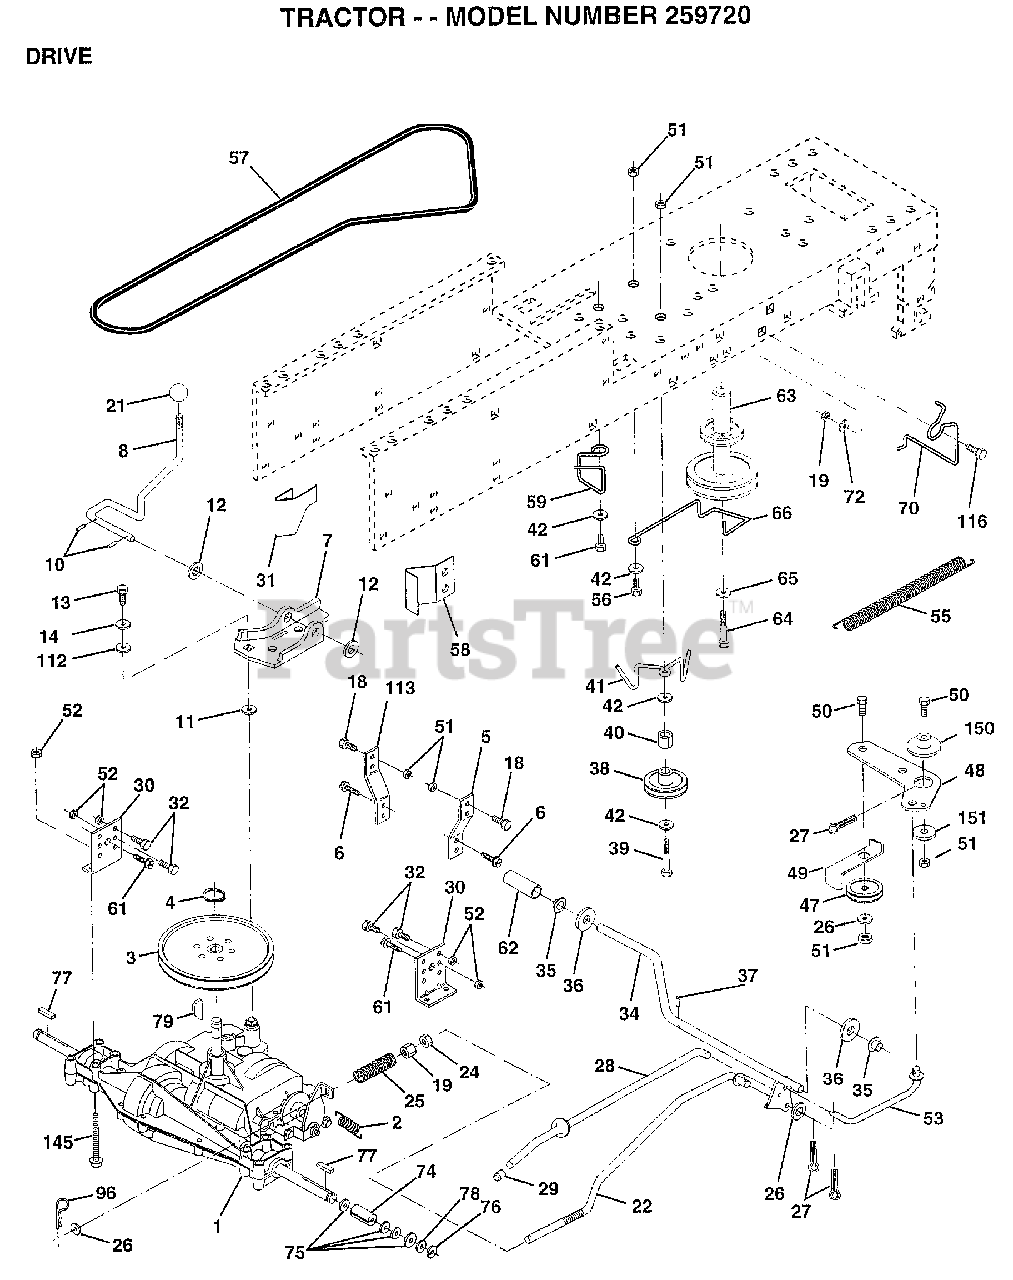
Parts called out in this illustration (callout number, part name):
2	SPRING.BRAKE.RETU
3	PULLEY TRANS
5	STRAP TORQUE
6	SCREW
7	BRKT.SADDLE.SHIFT
8	SHIFT ROD
10	PIN COTTER 1/8
11	WASH-SHFT PLT LT
12	WASHER
13	BOLT.1/4-28.W/PAT
14	LOCKWASHER
18	BOLT
19	NUT
21	KNOB T (1/2-HOLE)
22	BRAKE ROD
24	NUT
25	SPRING ROD LT
26	WASHER
27	COTTER PIN
28	ROD.BRAKE.PARK.LT
29	PLUNGER CAP T
30	TRANSAXLE MTG BKT
31	"KEEPER,BELT LH T"
32	BOLT
34	SHAFT ASM-PEDAL F
35	NYLON BEARING
36	WASHER LT
38	FLAT IDLER PULLEY
39	BOLT
40	SPACER T
41	"KEEPER,BELT.IDLER FLAT"
42	WASHER
48	BELLCRANK.CLUTCH
49	RETAIN BELT
53	"LINK, CLUTCH T"
55	"SPRING, RETURN LT"
58	"KEEPER,BELT RH T"
59	KEEPER BELT CNTSP
61	SCREW
62	PEDAL COVER T
63	PULLEY.ENGINE
64	BOLT
65	LOCKWASHER
66	KEEPER-BELT
70	KEEPER BELT ENG
72	WASHER
74	SPACER AXLE
75	WASHER
76	E-RING LT
77	SQUARE KEY
78	WASHER
96	RETAINER M
112	WASHER LT
113	"STRAP,TORQUE"
116	BOLT RDHD 3/8-16
145	BOLT.HEX.FLGHD
150	BUSHING.BELLCRANK.GRD.DR
151	WASHER
